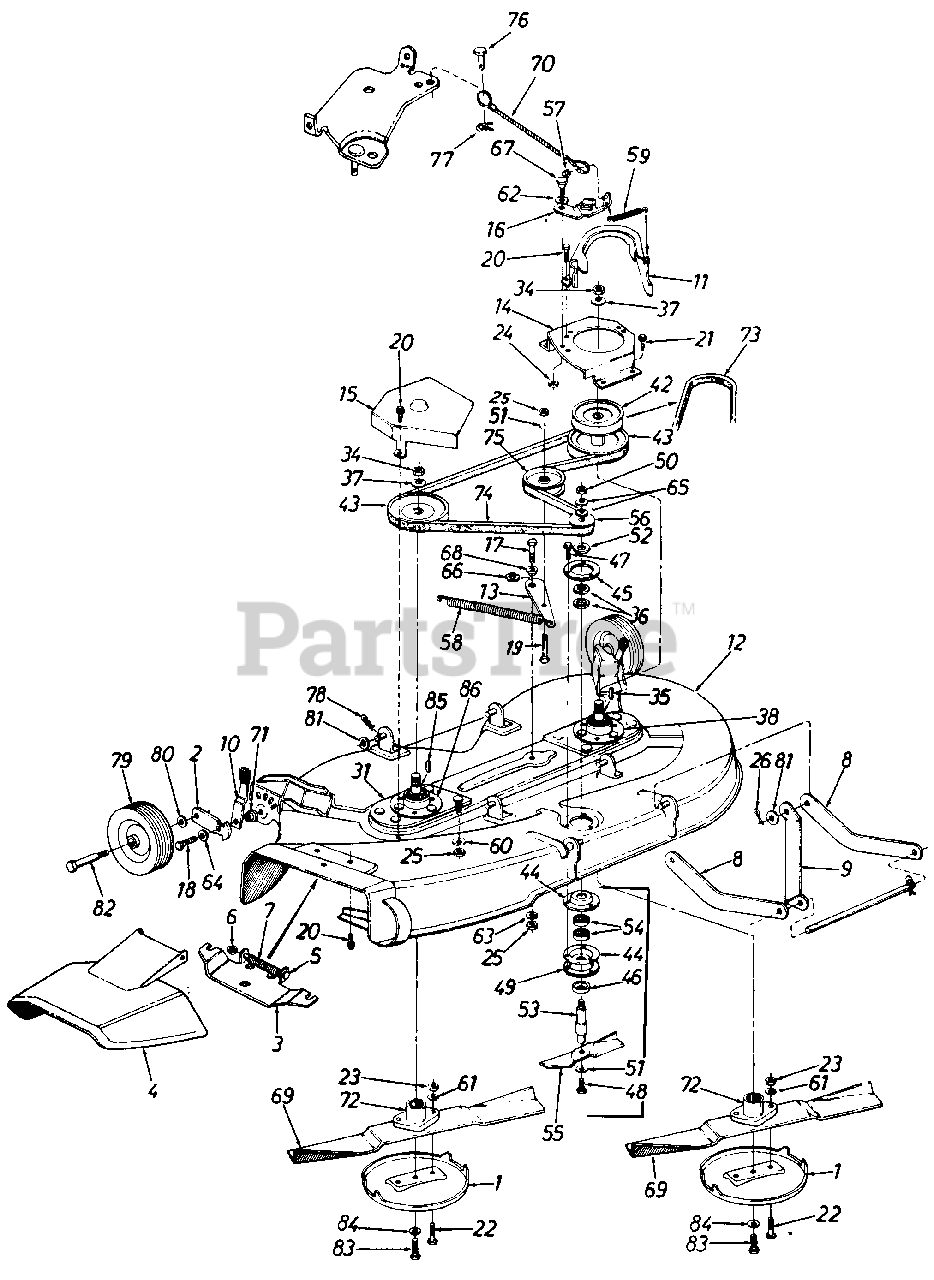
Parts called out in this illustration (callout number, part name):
1	Anti-Scalp Plate
2	Wheel Pivot Bar
4	Chute Cover Ass'y.
6	Cap Speed Nut 1/4" Rod.
7	Torsion Spring
11	Belt Guard
12	44" Deck Ass'y.
13	Idler Bracket
14	Pulley Cover-L.H.
17	Hex Bolt 3/8-24 x 1.00"
18	Hex Bolt 3/8-24 x 1.25"Lg.
19	Hex Bolt 3/8-24 x 1.50"
20	Hex Wash. S-Tapp Scr.1/4-20 x .SO"
21	Hex Wash. Hd. Tapp Scr. 5/16-18 x .75" Lg.
22	Hex Bolt 5/16-24 x 1.25" (Grade S)
23	Hex Nut 5/16-24 Thd.
24	Hex Cent. L.-Nut 5/16-18 Thd.
25	Hex Nut 3/8-24 Thd.
26	Cotter Pin 3/32 Dia. x 1.00" Lg.
34	Hex Jam Nut 5/8-18 Thd.
35	Square Key 3/16 x 2.25" 4
36	Fl. Wash. 5/8" I.D. x 15/16" O.D.
37	Bell. Wash.,630 I.D. x 1.25 x .090
38	L.H. Blade Spindle Ass'y. Comp.
42	5/8 "V"Pulley .79 I.D. x 5.75 O.D.
43	"V" Pulley .79 I.D. x 6.50 O.D.
44	1-3/8" I.D.-Bearing Housing
45	Reinforcement Plate
46	Bearing Shield
47	Hex "B" Tap Scr. .250" x 1.0" Lg.
48	Hex Cl.-Scr. 3/8-24 x .88 Lg.
49	Reinforcement Plate
50	Hex Jam Nut 1/2-20 Thd.
51	Bell.-Wash. .400 I.D. x .88 O.D. x.060
52	Fl.-Wash. .635 x 1.04 O.D. x .1 20"
53	6.5" Blade Spindle
54	Ball Brg. .62 I.D. x 1.30" O.D. x .44"
56	1/2" V-Pulley Half .625 I.D. x 2.25" O.D.
57	Cap Speed Nut 1/4" Rod.
58	Extension Spring .73 O.D. x 4.31 Lg.
59	Extension Spring
60	Bell.-Wash. .400 I.D. x .88 0 O.D. x .060
61	L.-Wash. 5/16" I.D.4
62	Spring Wash. .445 I.D. x .75 O.D. x .017
64	Bell.-Wash. .400 I.D. x 1.13 0 O.D. x .030
65	Bell.-Wash. .505 I.D. x 1.00 0 O.D. x.075
66	Spring Wash. .650 I.D. x .875 O.D. x .015 Thk.
67	Shld. Bolt .437 Dia. x .180
68	Shld. Spacer.625 I.D.
69	Mower Blade 21.88
70	Brake Cable Ass'y.
71	Shld. Spacer
72	Blade Adapter
73	"V"Belt 1/2 x 56" Lg.
74	"V"Belt 1/2 x 74" Lg.
75	Fl.-ldler w/Flanges 3.50 O.D.
76	Clevis Pin 1/4 Dia. x .53 Lg.
77	Intern. Cotter Pin 5/16" Dia.
78	Intern. Cotter Pin 1/2" Dia.
79	Deck Wheel 6.0 x 1.38
80	Bell.-Wash. .400 I.D. x .88 O.D. x .060
81	Fl.-Wash. .531 I.D. x .93 O.D. x .090
82	Shoulder Bolt 3/8-16 x 1.41
83	Hex Bolt 3/8-24 x .88" Lg.
84	L.-Washer 3/8 I.D.4
85	Sq. Key 3/16 x .75" Lg.
86	R.H. Blade Spindle Ass'y. Comp.
